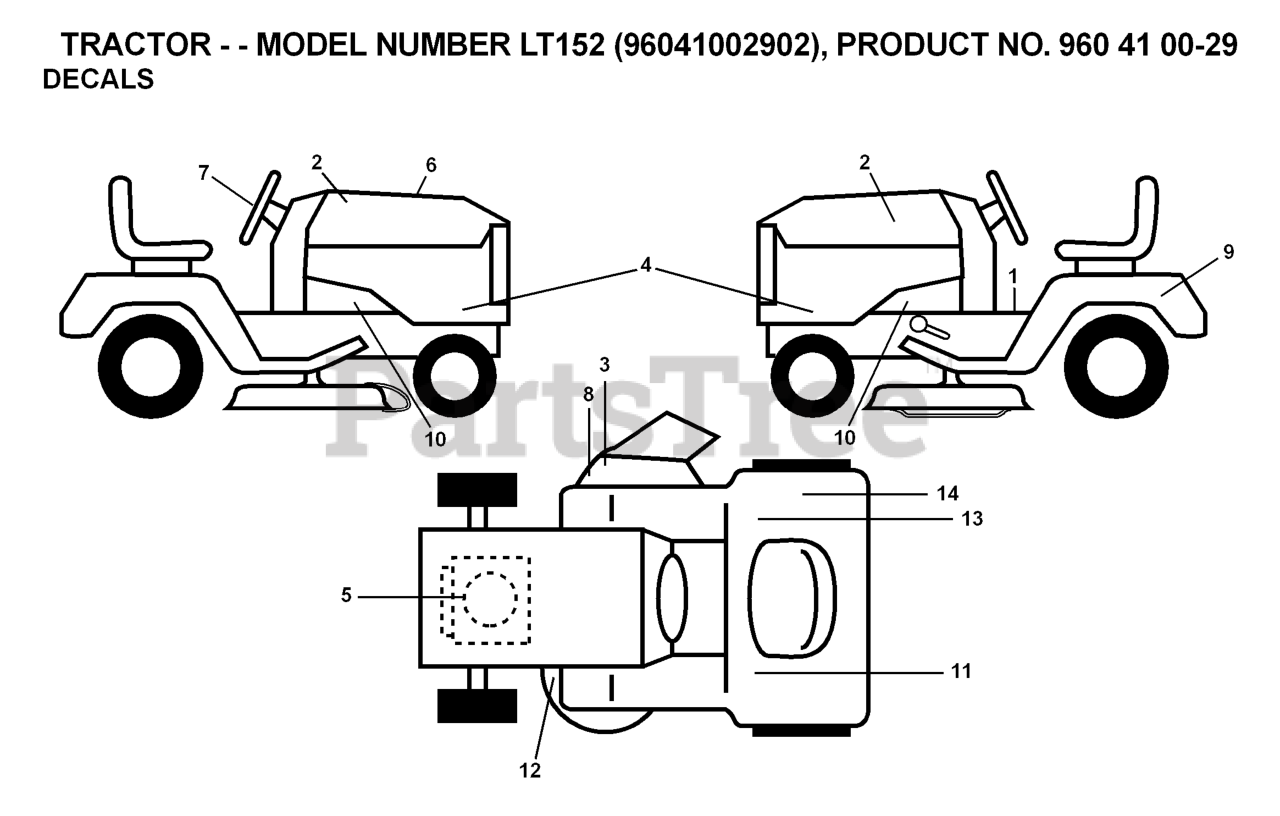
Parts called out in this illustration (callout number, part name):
1	LABEL
2	DECAL.HOOD.NAMELOGO.HUSQ
3	DECAL.INTERNATIONL.CUTFINGER
5	DECAL
7	DECAL.WHEEL.STRG.LGN.H
8	DECAL, DEFLECT WARNING
9	DECAL BTRY SYMBOLS
11	DECAL
12	DECAL V BELT SCHEMATIC
13	DECAL PARK BRAKE
14	Decal, Fender 100 DB/CE
